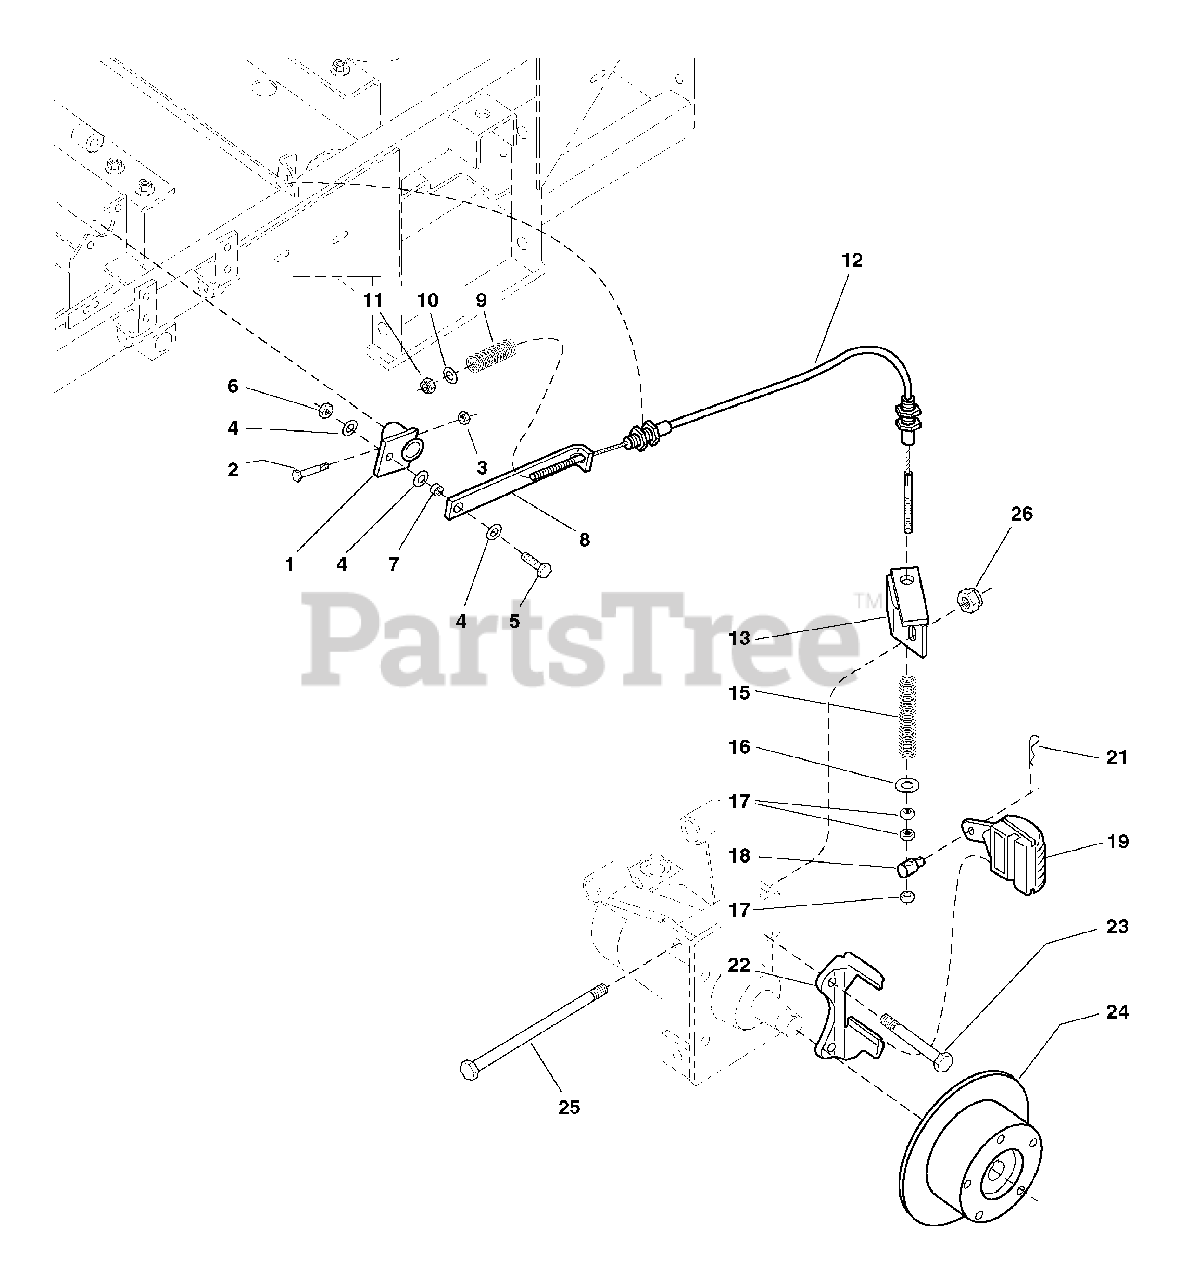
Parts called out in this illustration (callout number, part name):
1	BRAKE LINKAGE PIVOT (LH only)
2	CAPSCREW, Hex Hd, 1/4-20 x 1-3/4
3	NUT, Hex, Nylon Lock, 1/4-20
4	WASHER, 3/8
5	CAPSCREW, Hex Hd, 3/8-16 x 1-1/4
6	NUT, Hex, Nylon Lock, 3/8-16
7	SPACER, Pivot
8	LINK, Brake Lock
9	SPRING, Compression
10	WASHER, 5/16
11	NUT, Hex, Nylon Lock, 5/16-18
12	CABLE, Brake
13	BRACKET, Cable Mount-LH
15	SPRING, Compression
16	WASHER, Fender, 5/16
17	NUT, Hex, 5/16-24
18	ADJUSTER, Brake Linkage
19	BRAKE CALIPER, LH
20	BRAKE CALIPER, RH
21	HAIRPIN CLIP
22	MOUNT, Brake Caliper
23	CAPSCREW, Hex Hd, 1/2-20 x 3
24	HUB, 8" Brake Disc
25	CAPSCREW, Hex Hd, 1/2-13 x 7-1/2
26	NUT, Hex, Nylon Lock, 1/2-13
